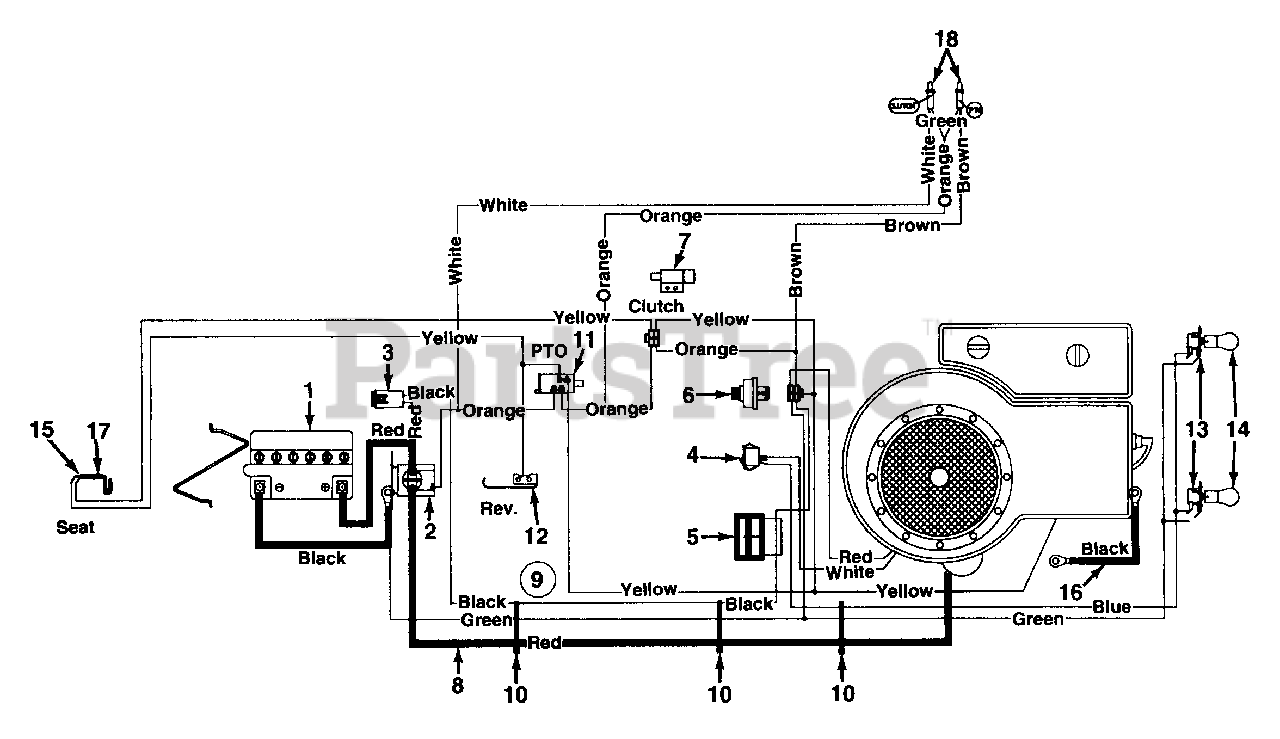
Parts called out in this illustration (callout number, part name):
1	Battery
2	Solenoid
3	Fuse 7.5 Amps
4	Light Switch
5	Ammeter
6	Ignition Switch
7	Safety Switch (Clutch)
8	Electric Wire 30" Lg.
9	Wire Harness
11	Safety Switch (Deck)
12	Safety Switch (Reverse)
13	Socket
14	Bulb (Headlight)
15	Safety Switch (Seat)
16	Ground Wire 7.5" Lg.
17	Safety Switch (Seat)
18	Bulb (Monitor)
